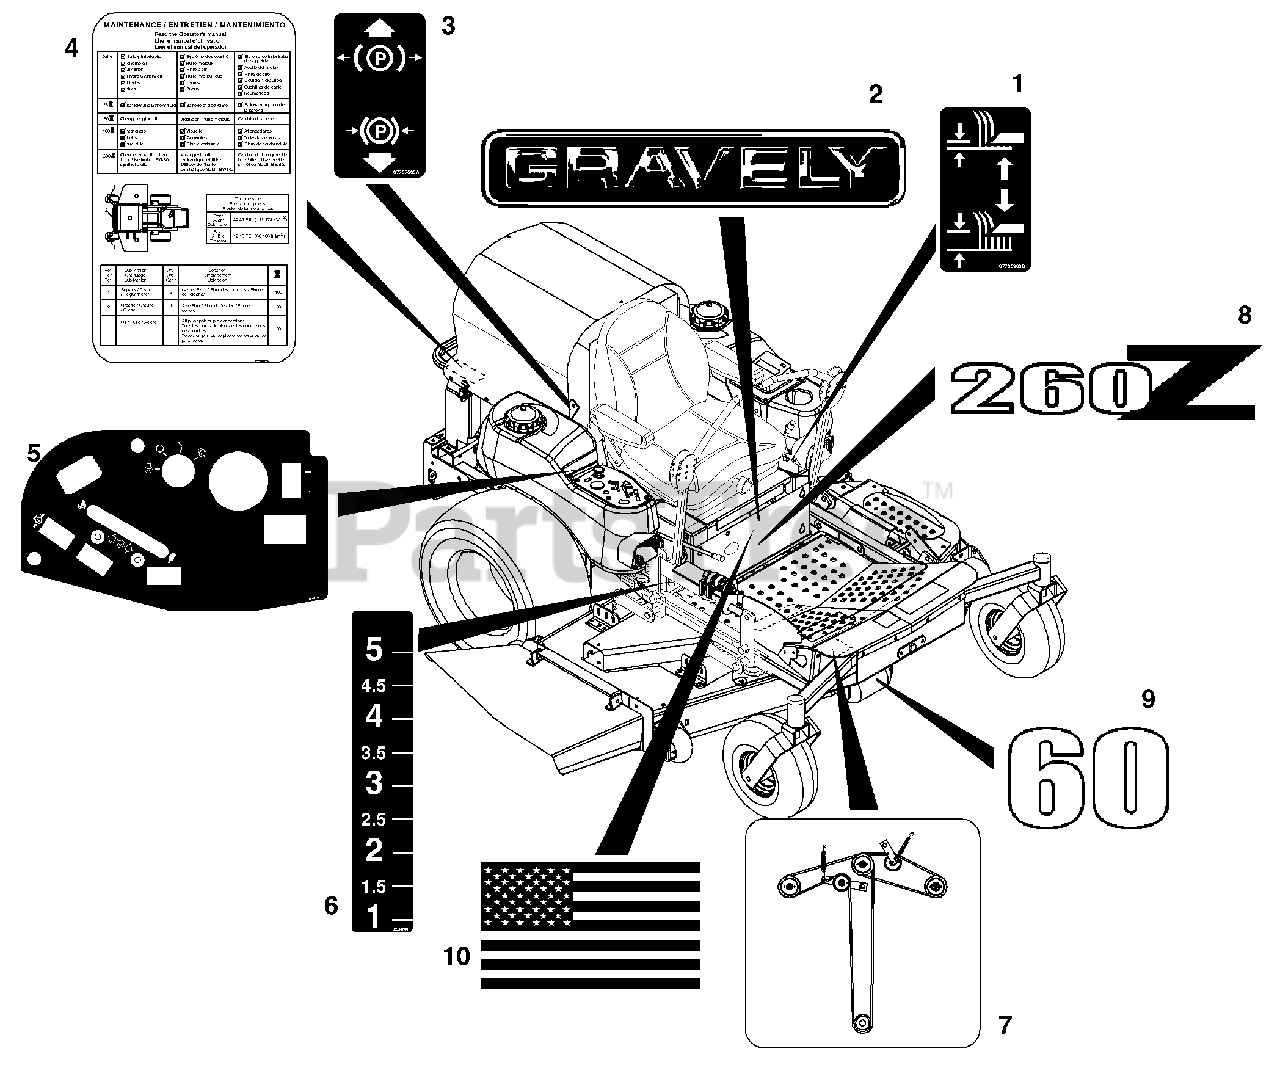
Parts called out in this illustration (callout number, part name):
1	Decal, Lift Lever
2	Decal, 15" Gravely Logo
3	Decal, Parking Brake Lever
4	Decal, Service Instructions
5	Decal, Diesel Control Panel (075, 076, 318, 319)
5	Decal, Control Panel (073, 074)
6	Decal, Height of Cut
7	Decal, Belt Diagram (073, 075, 318, 319)
7	Decal, Belt Diagram (074, 076)
8	Decal, PM-260Z (073, 075, 318, 319)
8	Decal, PM-272Z (074, 076)
9	Decal, 60 (073, 075, 318, 319)
9	Decal, 72 (074, 076)
10	Decal, American Flag
